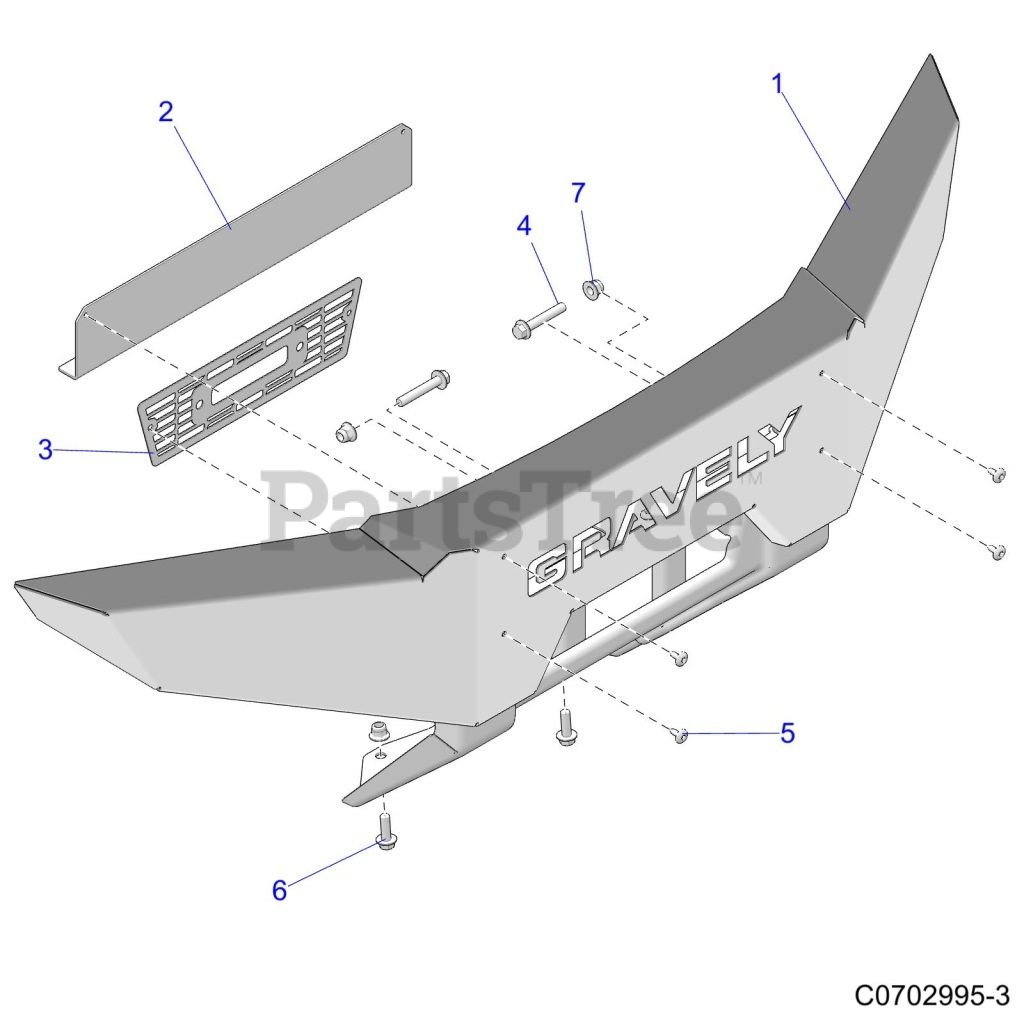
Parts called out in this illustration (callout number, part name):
1	WELD-BUMPER,FRONT,ARIENS,M BLK
2	PLATE, GRAVELY RED
3	SCREEN-BUMPER,BLK
4	BOLT-M10X1.25X60,HXFLG-OLIVE D
5	SCR-M6X1X16 TR/TX-M
6	SCR-HXFL-M10X1.25X30 8.8 ZOD
7	NUT-M10X1.25,FLG,NYLOC-OLIVE D
